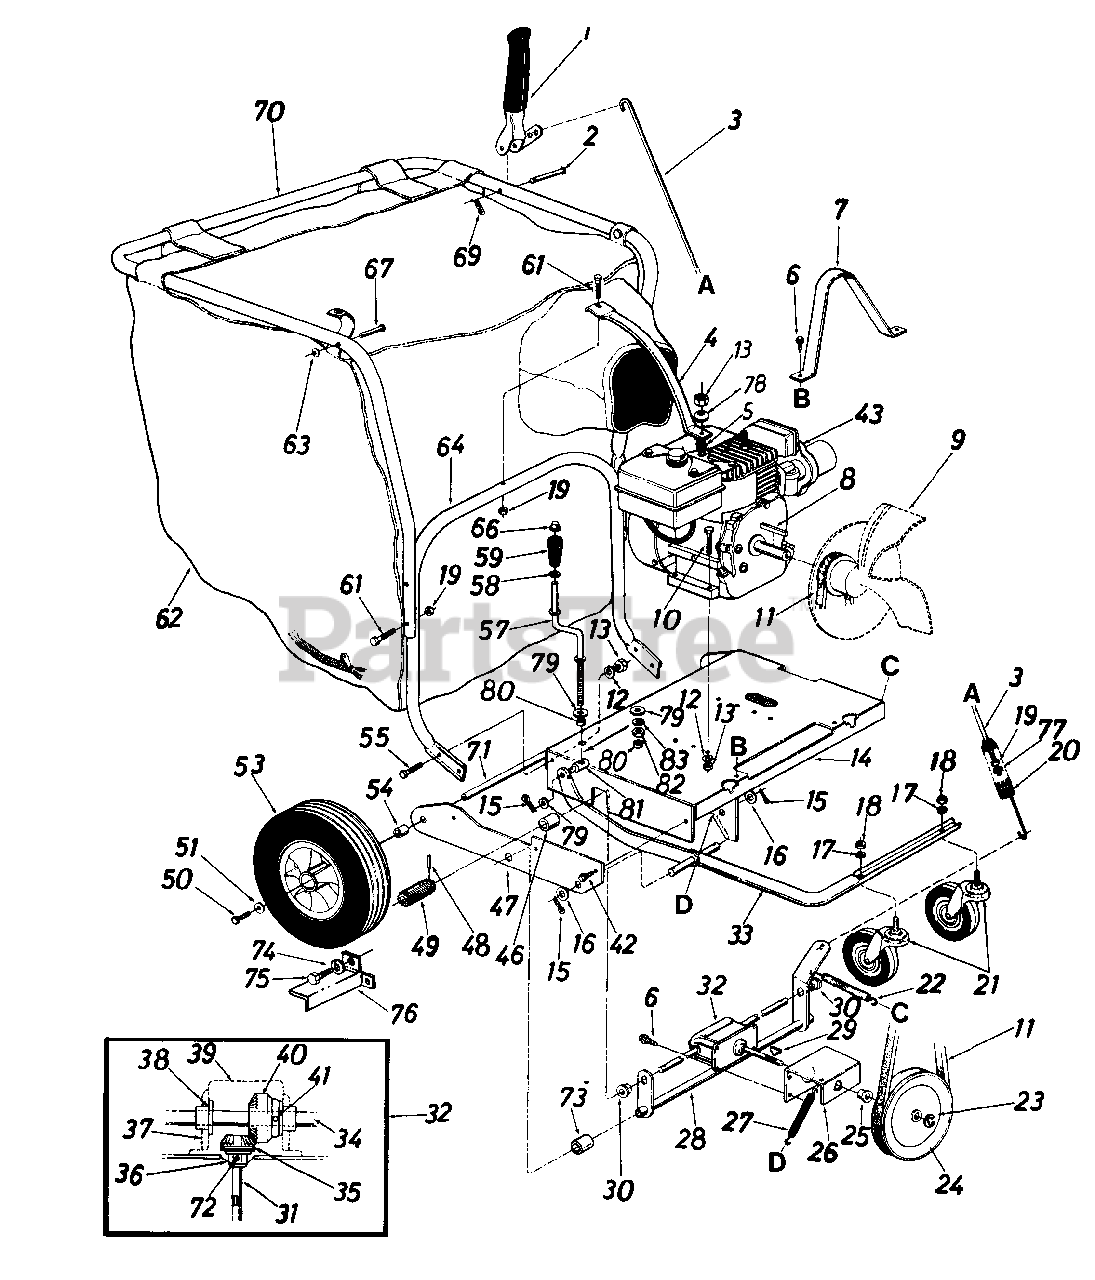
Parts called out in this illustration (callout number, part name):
1	Clutch Grip Ass'y.
2	Clevis Pin .375" Dia. x 1.88"
3	Clutch Rod 32" Lg.
4	Handle Brace
5	Part of Engine
6	Hex Wash. Hd. AB-Tap Scr. 1/4" x .62" Lg.
9	Air Vane Plate Ass'y. w/Pulley
10	Hex Bolt 5/16-18 x 1.5" Lg.
11	"V"-Belt
12	L-Wash. 5/16" I.D.
13	Hex Nut 5/16-18 Thd.
16	Fl-Wash. .63" I.D. x 1.25" O.D.
17	L-Wash. 1/2" I.D.
18	Hex Nut 1/2-13 Thd.
19	Hex Cent. L-Nut 1/4-20 Thd.
20	Extension Spring .78" O.D. x .75" Lg.
21	Swivel Caster Wheel 5" Dia. x 1 .25"
22	Extension Spring .38" O.D. x 7.50" Lg.
23	Snap "E"-Ring .50" Dia. Shaft
24	"V"-Pulley 5/8" x 6.50" O.D.
25	Flange Bearing .502" I.D.
28	Clutch Bracket Ass'y.
29	#2 Woodruff Key 3/32" Dia. x .81" Lg.
30	Hex Flange Bearing Bronze .625" I.D.
31	Pinion Shaft .50" Dia. x 5"
32	Gear Box Ass'y. Comp.
35	Bevel Gear .50" I.D. x 14 Teeth
36	Flange Bearing .503" I.D.
37	Gear Box
38	Flange Bearing .630" I.D.
39	Gear Box Cover
40	Bevel Gear .62" I.D. x 28 Teeth
41	Spring Pin Spiral 3/16" Dia. x 1.25" Lg.
42	Hex Wash Hd AB-Tap Scr. 5/16" x .75" Lg.
43	Engine
46	Spacer .63" I.D. x .88" O.D. x .56" Lg.
49	Drive Pinion
50	Hex Locking Bolt 5/16-24 x .62" Lg.
51	Fl-Wash. .34" I.D. x .87" O.D.
53	Wheel Ass'y. Comp. 12" x 3"
54	Spacer .63" I.D. x 1.0" O.D. x .94" Lg.
55	Hex Bolt 5/16-18 x .75" Lg.
57	Height Adjustment Crank
58	Fl-Wash. .385" I.D. x .62" O.D.
59	Crank Knob
61	Hex Bolt 1/4-20 x 1.75" Lg.
62	Vacuum Bag--Felt
63	Push Speed Nut .25" Dia. Stud
67	Stud Pin .250" Dia. x 1.75"
69	Internal Cotter Pin 3/8" Dia.
70	Upper Handle
71	Rear Axle
72	Spring Roll Pin 5/32" Dia. x 1.12
73	Spacer .82" I.D. x 1.0" O.D. x .305 Lg.
74	L-Wash. .265" I.D.
75	Hex Self-Tap Scr. 1/4" x 3/8" Lg.
78	Belleville Washer
79	Fl-Wash. .35" I.D. x .87" O.D.
80	Spacer .38" I.D. x .50" O.D. x .18" Lg.
81	Ferrule 3/8-8 x .38" Dia.
82	Hex Nut 3/8-8 Thd.
83	L-Wash. 3/8" I.D.
